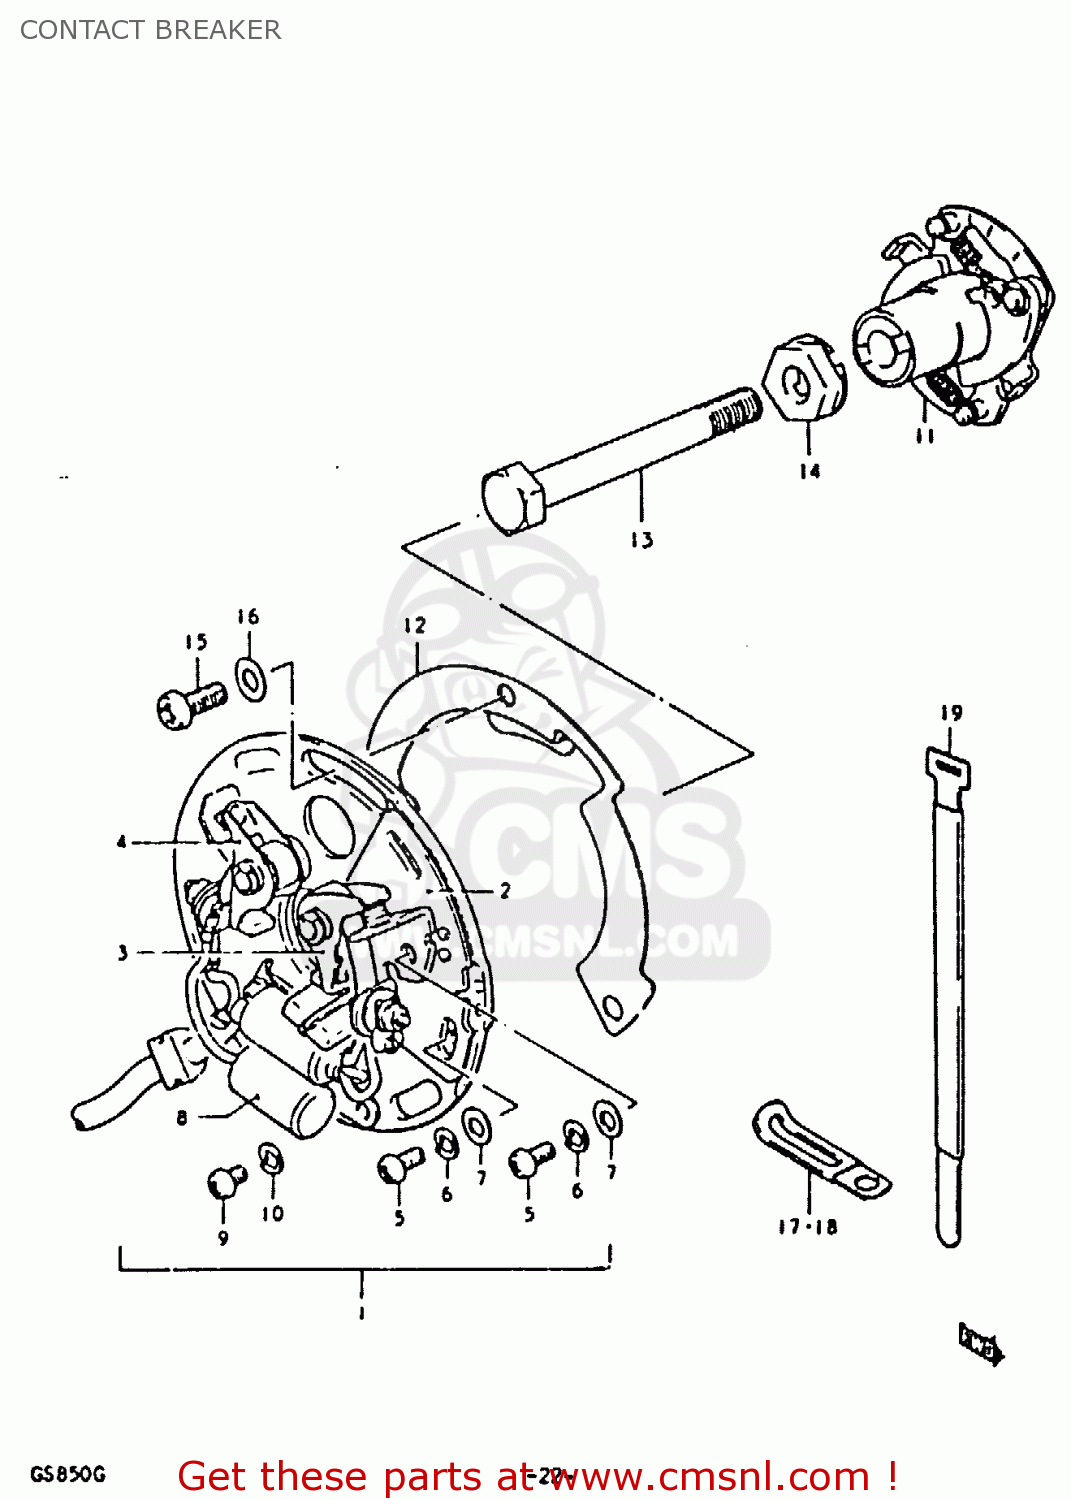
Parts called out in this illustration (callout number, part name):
1	BREAKER ASSEMBLY,CONTACT
2	PLATE,CONTACT POINT
3	POINT ASSY,R
4	POINT ASSY,L
5	SCREW(4X10)
6	LOCK WASHER
7	WASHER
8	CONDENSER
9	SCREW
10	LOCK WASHER
11	GOVERNOR ASSEMBLY
12	PLATE,IGNITION TIMING
13	BOLT
14	WASHER
15	SCREW(5X12)
16	WASHER 5MM
17	CLAMP L:35
18	CLAMP
19	CLAMP
